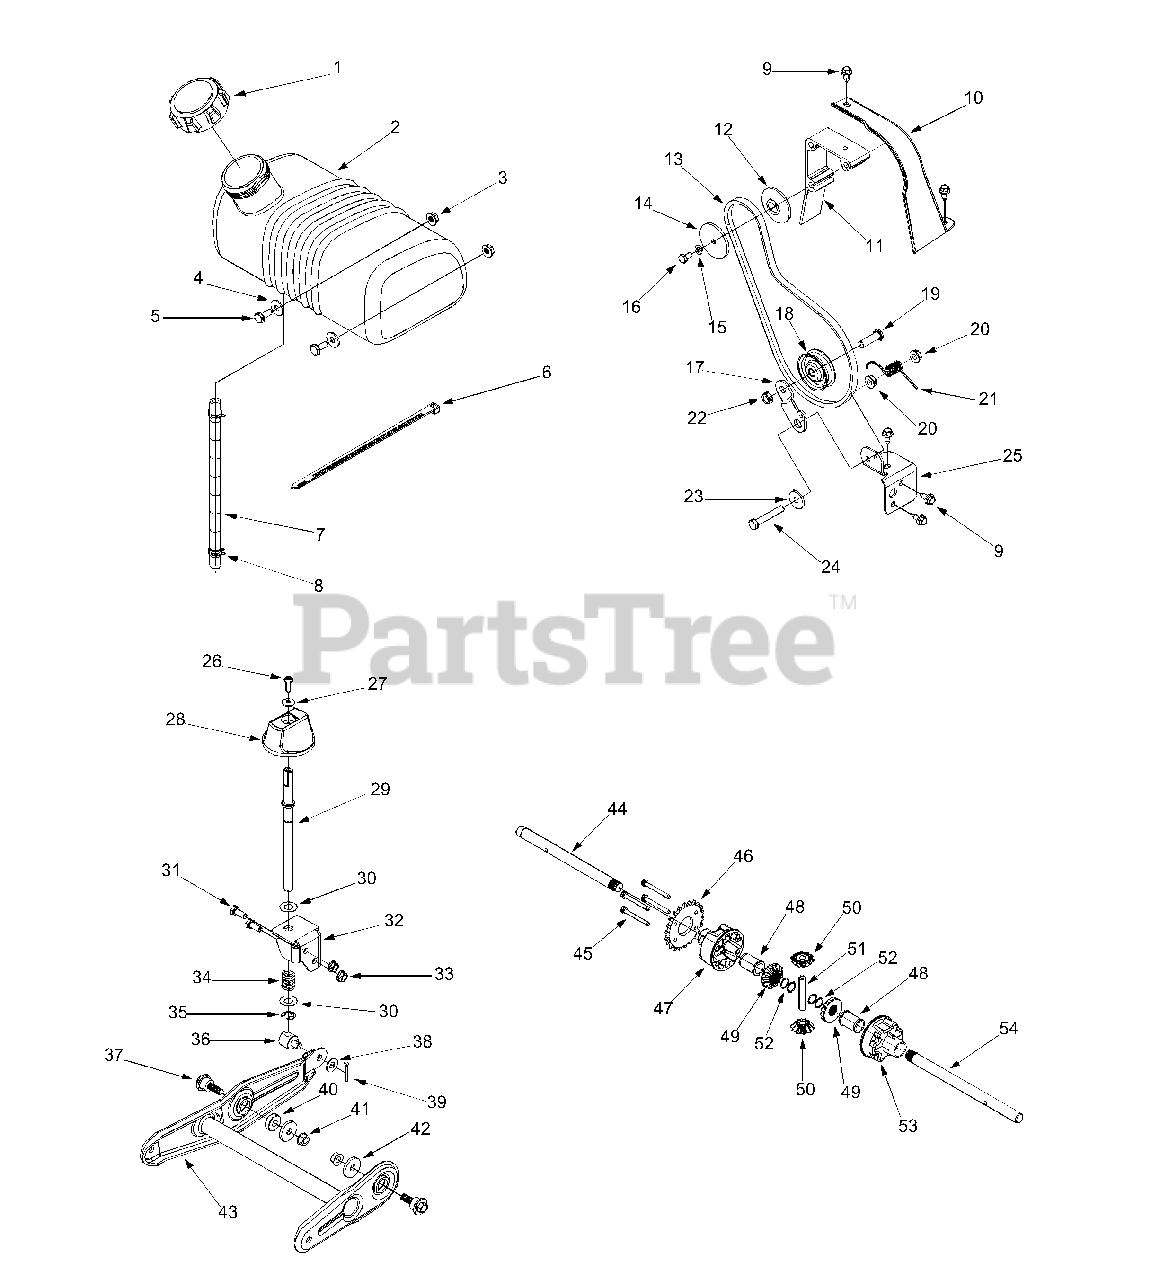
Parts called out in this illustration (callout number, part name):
1	Fuel Cap
2	Gas Tank - 1 Gallon
3	Hex Lock Nut 1/4-20
4	Flat Washer .28 ID x .74 OD
5	Hex Cap Screw 1/4-20 x .620
6	Cable Tie
7	Fuel Line
8	Hose Clamp
9	Hex Washer Screw 1/4-14 x .625
12	Pulley Half
13	V-Belt
14	Pulley Half
15	Lock Washer 1/4
16	Hex Cap Screw 1/4-28 x .50
17	Idler Bracket
18	Flat Idler
19	Hex Cap Screw 3/8-16 x 1.25
20	Hex Lock Nut 5/16-18
21	Torsion Spring
22	Lock Nut 3/8-16
23	Shoulder Spacer
24	Hex Cap Screw 5/16-18 x 2.0
27	Bell Washer .265 ID x .75 OD
29	Height Adjustment Rod
30	Flat Washer .508 ID x 1.0 OD
31	Hex Cap Screw 5/16-18 x .75
34	Compression Spring
35	E Ring
36	Adjustment Ferrule
37	Shoulder Screw 3/8-16
38	Flat Washer .406 ID x .875 OD
39	Cotter Pin
40	Spacer
41	Flange Lock Nut 3/8-16
42	Flat Washer .375 ID x 1.25 OD
45	Hex Washer Screw 1/4-20 x 2.375
46	Sprocket 22T
47	Differential Housing LH
48	Flange Bearing .75 ID x 1.0 OD x 1.5
49	Differential Gear 14T
50	Differential Gear 10T
51	Cross Shaft .427 x 2.7
52	Retaining Ring
53	Differential Housing RH
54	Axle Shaft .750 x 10.954
